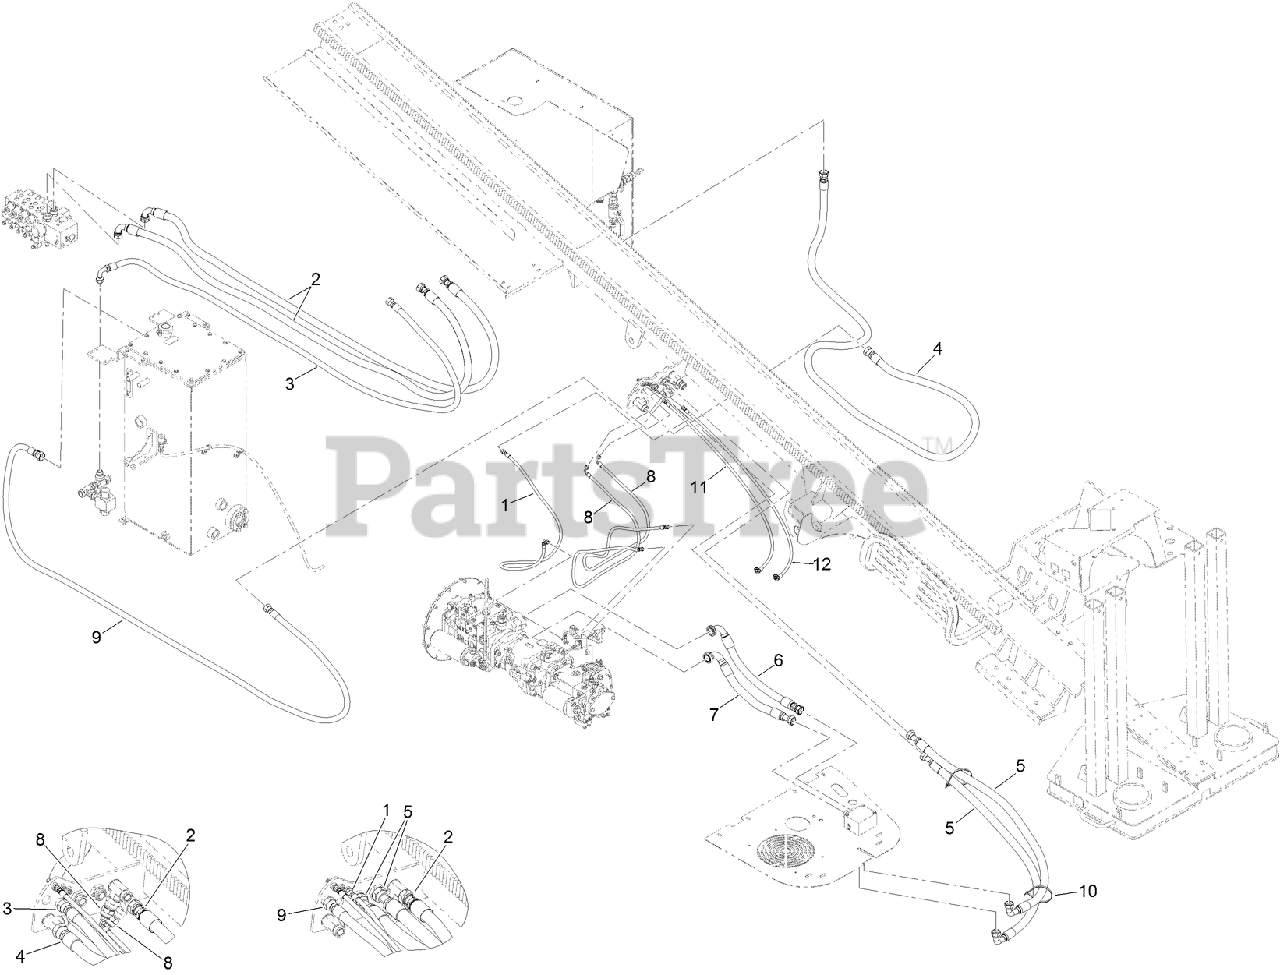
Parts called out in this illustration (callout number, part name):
1	HOSE ASM-HYD
2	HOSE ASM-HYD
3	HOSE ASM-HYD
4	HOSE ASM-HYD
5	HOSE ASM-HYD
6	HYD HOSE ASM
7	HOSE ASM-HYD
8	HOSE ASM-HYD
9	HOSE ASM-HYD
10	TIE-CABLE
11	HYD HOSE ASM
12	HYD HOSE ASM
